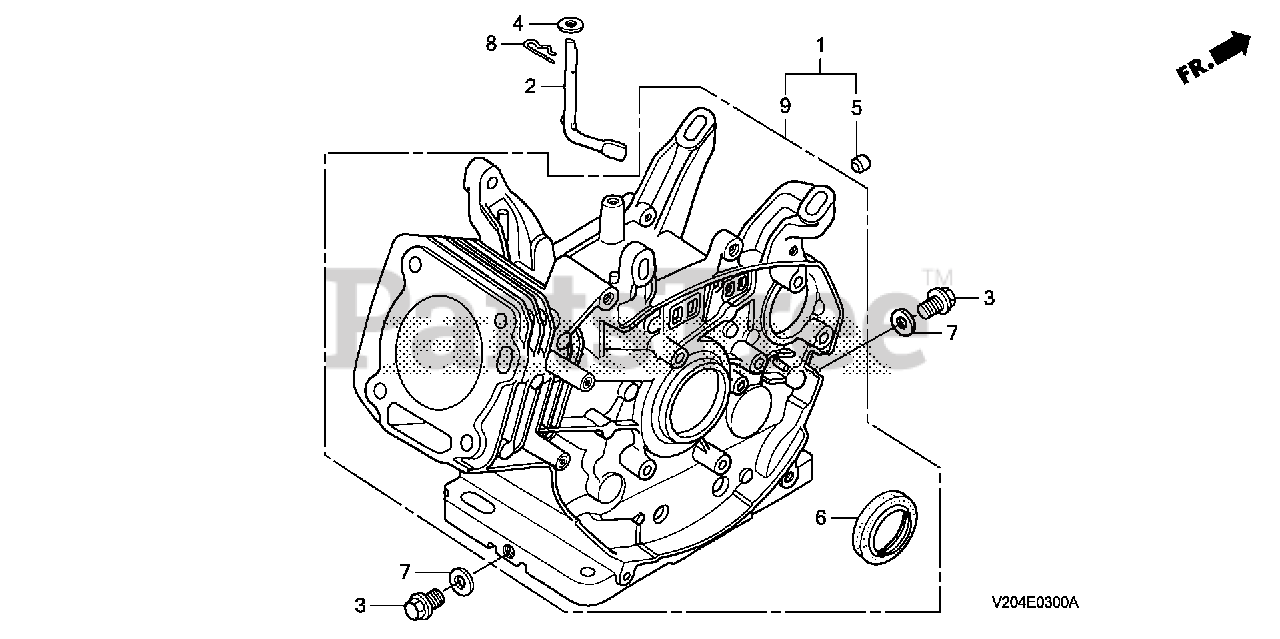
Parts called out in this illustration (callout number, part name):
2	SHAFT, GOVERNOR ARM
3	BOLT, DRAIN PLUG
4	WASHER (8.2X17X0.8)
6	OIL SEAL (30X46X8)
7	WASHER, DRAIN PLUG (12MM)
8	PIN, LOCK (10MM)
9	CYLINDER ASSY. (STD)
